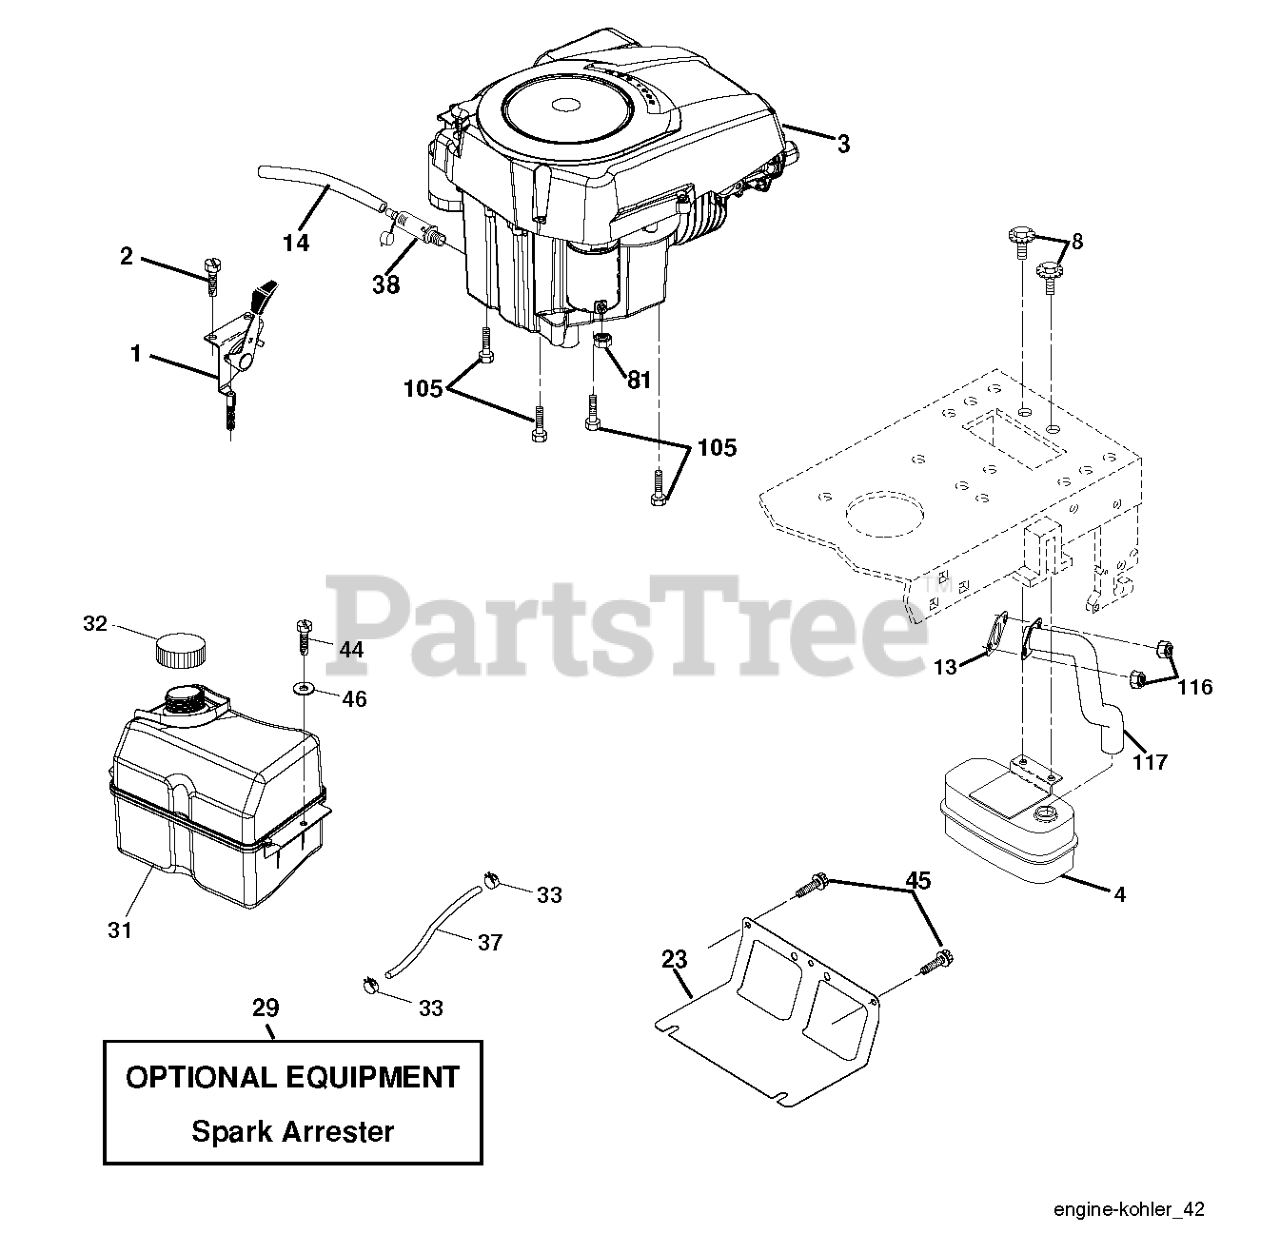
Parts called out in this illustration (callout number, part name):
1	CONTROL.THROTTLE.LT/YT
2	SCREW
4	MUFFLER.SINGLE.CYL.KOHL/B&S
8	BOLT.5/16-18UNCX3/4 W/SEMS.BLK
13	GASKET.EXHAUST.KOHLER
14	TUBE, DRAIN OIL ASM.
23	SHIELD.BROWNING.DBR.GUARD
29	KIT.SPARK ARRESTOR 794945 B&S
31	TANK FUEL
32	FUEL CAP
33	HOSE CLAMP
37	LINE.FUEL.20
38	PLUG DRAIN OIL EASY
40	BUSHING.SNAP.NYL.BLK.
44	SCREW HEXWSHR 1/4-20X3/4
45	SCREW, 3/8-16X3/4
72	SCREW.SOCKET HD.5/16-1
81	NUT
105	SCREW 3/8-16X1
117	RP.TUBE.EXHAUST.KOHL.COURAGE
